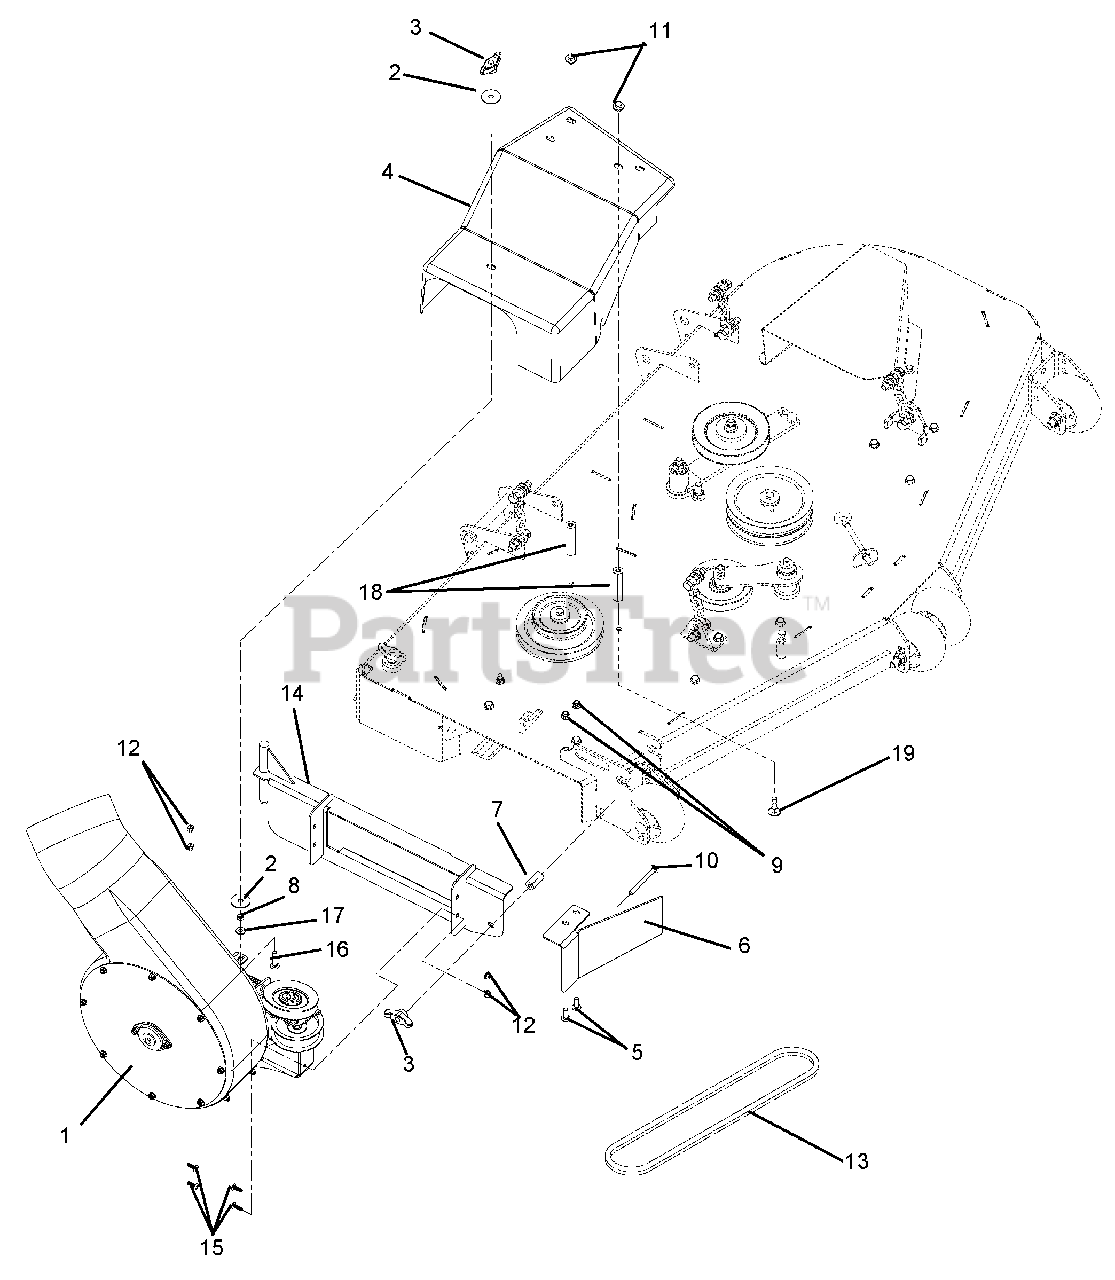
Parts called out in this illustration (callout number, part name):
1	Housing, Blower
2	Washer, Flat-Steel .38 x 1.50 x .062
3	Knob, Clamping Nyloc .312-18
4	Belt Cover (with 52" and 60" Adapter Kits)
5	Bolt, Round Head Square Neck .31-18 x 1 Grade 5 (with 60" Adapter Kit 79102500)
6	Baffle, 60" HD Bagger (with 60" Adapter Kit 79102500)
7	Spacer, CZ-Head Bagger
8	Nut-Jam .312-18
9	Nut, .31-18 Nyloc Flange (with 60" Adapter Kit 79102500)
10	Bolt, Round Head Square Neck .38-16 x 1.00
11	Bolt, SEMS .31-18 x .62
12	Nut, Locking-Top-Flange .25-20
13	Belt, 4L 70.81 Raw (for 60" Decks)
14	60" HD Bag Pump Mounting Bracket Weldment (with 60" Adapter Kit 79102500)
15	Screw, Machine .25-20 x .75
16	Bolt, Round Head Square Neck .31-18 x 1.50
17	Washer, Flat Steel .312 x .734 x .065
18	Nut, Coupling .31-18 x 3.00
19	Bolt, Round Head Square Neck .31-18 x .75 with Epoxy Patch
